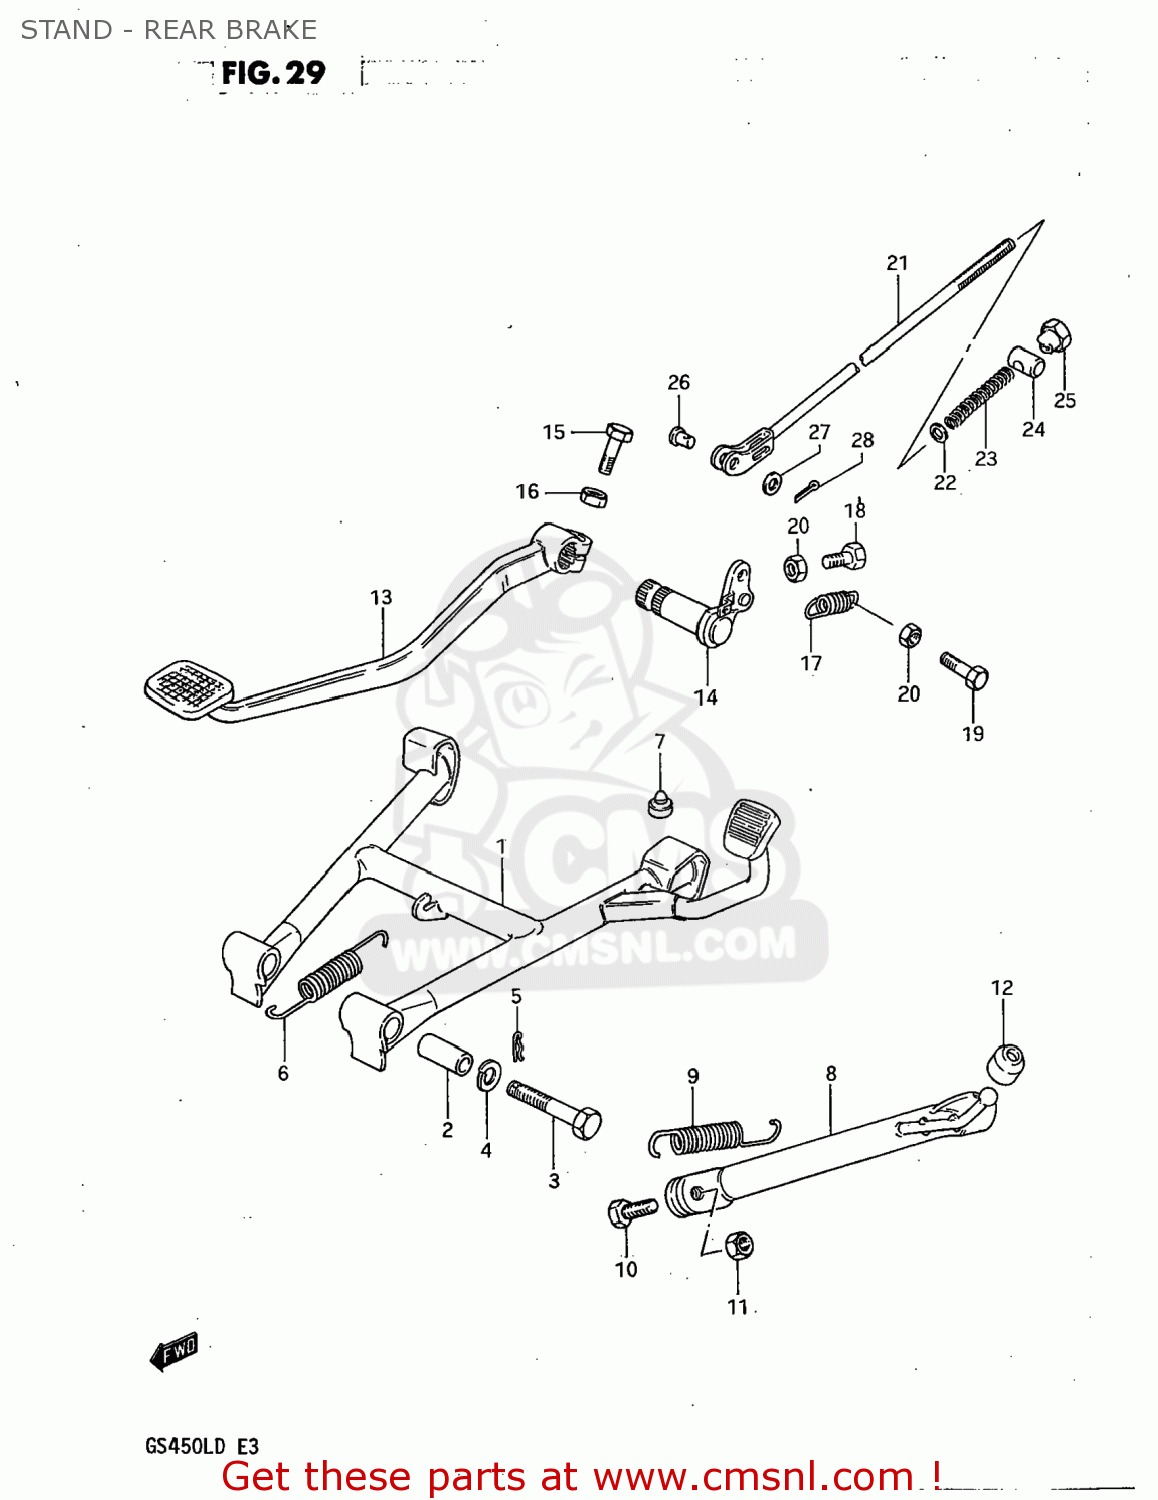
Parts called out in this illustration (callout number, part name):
1	STAND,CENTER
2	SPACER(10X16X38.8)
3	BOLT
4	LOCK WASHER
5	CLIP
6	SPRING
7	CUSHION
8	STAND,SIDE
9	SPRING
10	BOLT(10X30)
11	NUT
12	CUSHION
13	PEDAL,BRAKE
14	ARM,BRAKE PEDAL
15	BOLT
16	LOCK WASHER
17	SPRING
18	BOLT
19	BOLT
20	NUT
21	ROD ASSY,RR BRAKE
22	WASHER
23	SPRING
24	PIN
25	NUT
26	PIN(L:13.5)
27	WASHER
28	PIN 20X20
